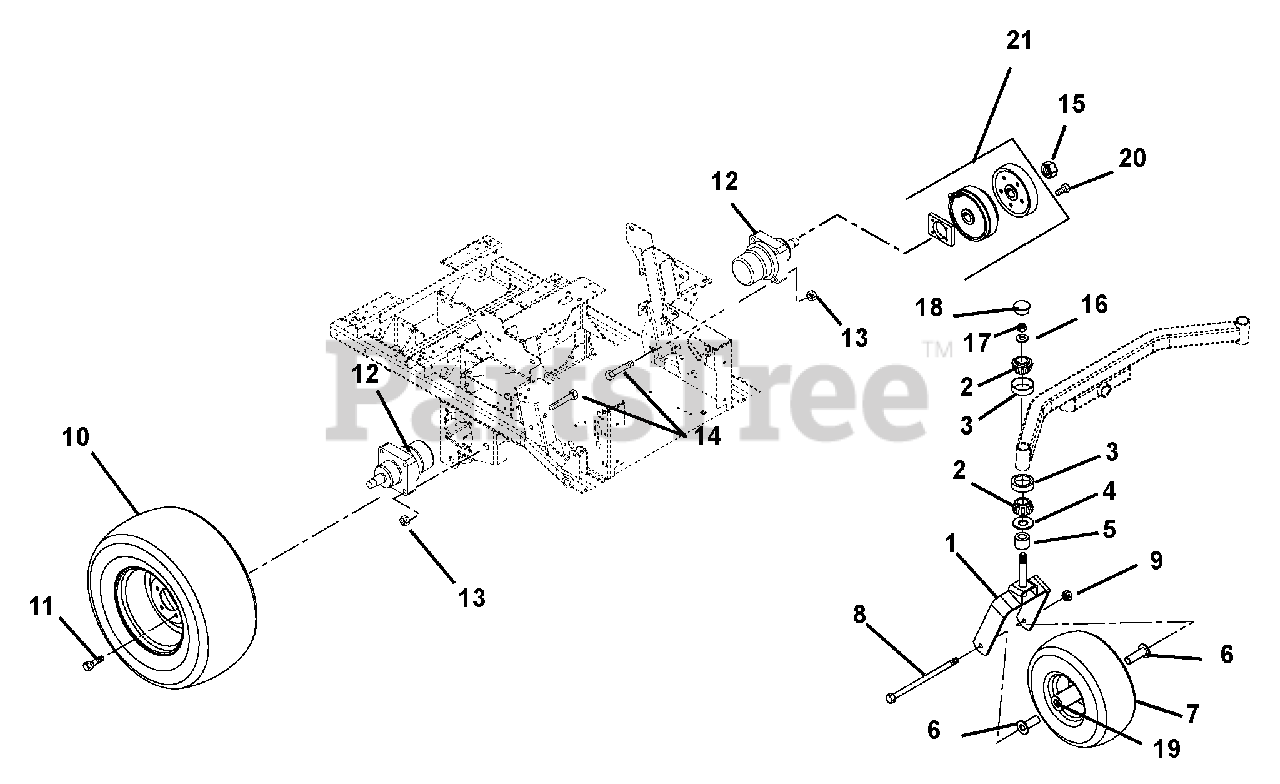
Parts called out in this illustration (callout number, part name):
1	Fork, Front
2	Bearing, Cone w/ Grease
3	Bearing, Cup 1.980 x .420
4	Bearing Seal 1.5 x 2 x .18
5	Spacer, PM, 1.03 I.D. x 1.5 O.D. x .375
6	Spacer, Wheel
7	Wheel/Tire Assembly 15 x 6-6
7	Tire, 15 x 6-6
8	Bolt, Hex .50-13 x 9.00 Grade 5
9	Nut, Locking Center .50-13
10	Tire/Wheel Assembly 24 x 12-12
10	Tire, Turfmaster 24 x 12-12
11	Bolt, Lug .50-20 x 1.38 Grade 8, 60 Degree
12	Hydraulic Wheel Motor
13	Nut, Locking Top Flange .50-13
14	Bolt, Wheel Motor .50-13 x 2.75
15	Nut , Lock Jam Patch
16	Washer, Flat Steel 812 x 1.50 x .135
17	Nut, Jam Center-Lock .75-16
18	Cap, Dust
19	Bearing, 25mm I.D. x 52mm OD x 15mm
20	Bolt, Hex .31-18 x 1.5 Grade 5
21	Kit, Parking Brake Service
